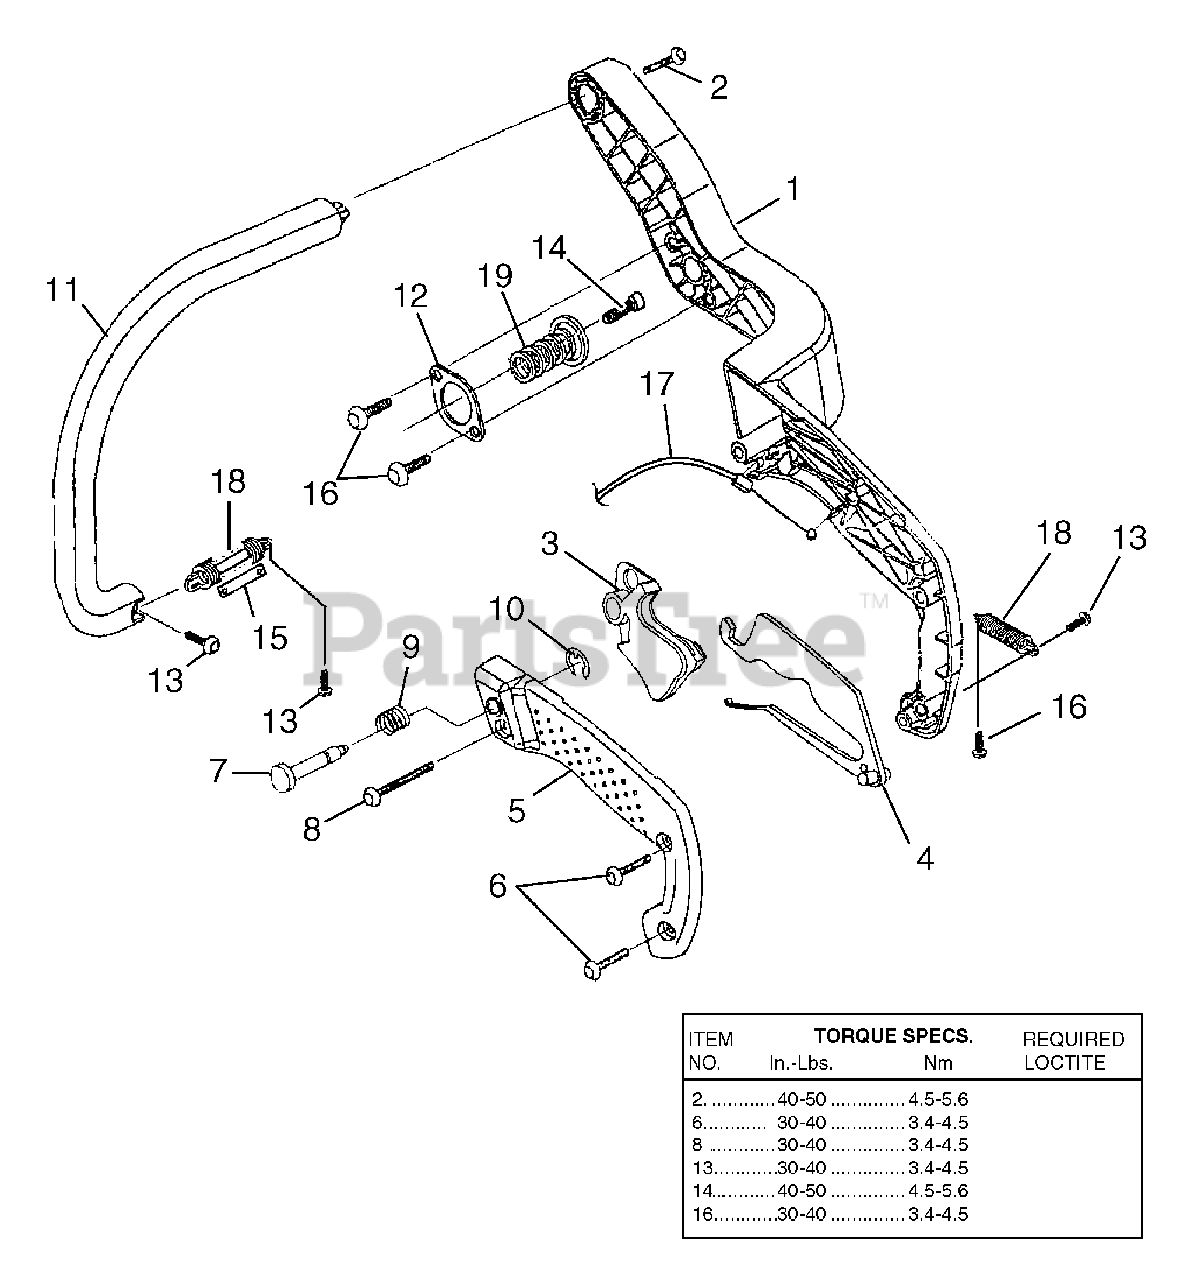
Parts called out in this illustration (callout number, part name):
1	REAR HANDLE
2	SCREW (12-14 x 1-1/2 in.)
3	THROTTLE TRIGGER
4	THROTTLE LOCK OUT
5	HANDLE COVER
6	SCREW (10-14x3/4 in.)
7	THROTTLE PIN LOCK
8	SCREW (10-14 x 1- 3/8 in.)
9	SPRING
11	FRONT HANDLE
12	ISOLATOR PLATE
13	SCREW (10-14 x 5/8 in.)
14	SCREW (10-24 x 5/8 in.)
15	LIMITER, ISOLATOR
16	SCREW (10-14 x 1/2 in.)
17	THROTTLE CABLE
18	EXTENSION SPRING
19	UPPER ISOLATION SPRING
